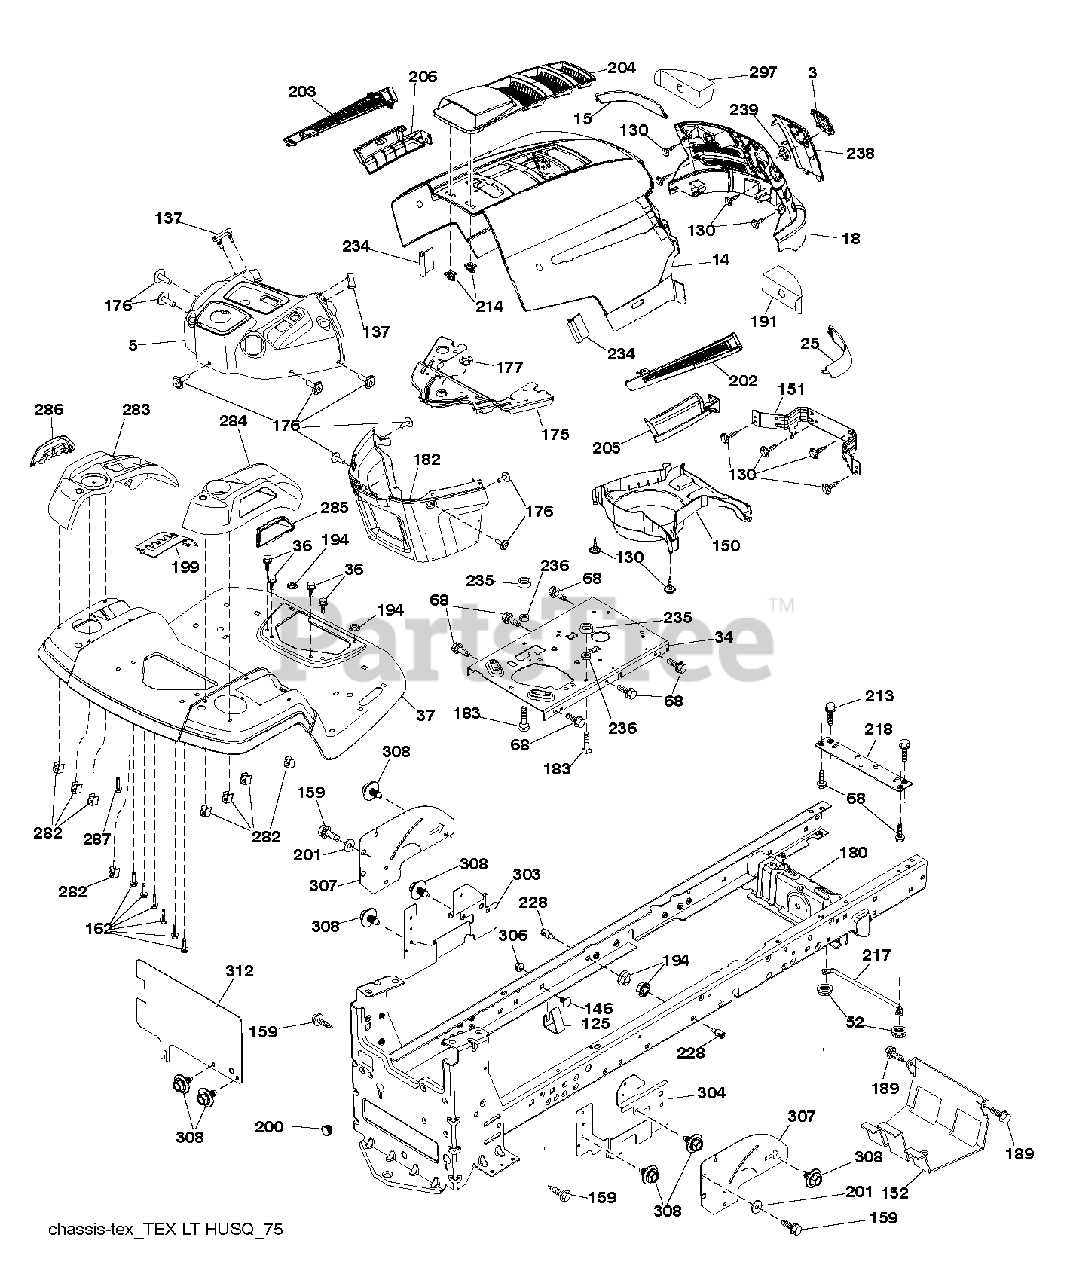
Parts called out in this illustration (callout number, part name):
3	LOGO.HUSQ.GT.LT.CROWN.H
5	DASH.HUSLT.PTO.RS.CHG.SRV.498
14	HOOD.HUSQVARNA.LT.ORANGE
15	LENS.HUSQVARNA LT.RH
18	GRILLE.SVC.HUSQVARNA.GREY
25	LENS.HUSQVARNA LT.RH
34	PLATE.ENGINE.WELDED.CHASSIS
36	SCREW 5/16"
37	FENDER.TLT.FS.W/CUPHLD.ORANGE
52	LOCKNUT
68	SCREW LT
125	CLIP.FUEL.LINE
130	SCREW.#10 X 0.750.BOS
137	BUMPER DASH
146	BOLT.RDHD.SHT.SQNK.3/8-16X5/8
151	BRACKET PIVOT
152	SHIELD.BROWNING.W/TEX
159	SCREW, 3/8-16X3/4
162	SCREW.HI-LO.CONSOLE
175	CROSSMEMBER
176	SCREW.#10-24X5/8.RN.QU
177	BUSHING STEERING
180	CHASSIS
182	DASH.LOWER.PREDATOR LT
183	BOLT.5/16-18X1-1/4 FULL THD
189	SCREW
191	INSERT.REFLECTIVE.RH.
194	NUT LOCK HEX FLANGE 5/16-18
199	PLATE.DECK.LIFT.HUSQ.LT
200	PLUG.DEMO.625
201	WASHER
202	VENT.SIDE.HUSQVARNA.LT.RT
203	VENT.SIDE.HUSQVARNA.LT.LFT
204	SUBASM.TOP.VENT.HUSQ.LT
205	SKIRT.SIDE.HUSQVARNA.LT.RT
206	SKIRT.SIDE.HUSQVARNA.LT.LEFT
213	BOLT
214	CLIP.RETAINER.TINNER.
217	ROD.PIVOT.HOOD
218	X-PIECE.HOOD.STOP.NON/
228	STUD.FASTNER.W/ANTI-ROTATE
234	BUMPER.HOOD.TEX.HUSQVARNA
235	SPACER FENDER
236	NUT.CENTERLOCK.5/16-
238	TRIM.HUSQ LT.668
282	CLIP.RETAINER.CONSOLE.LT.HUSQ
283	CONSOLE.ASM.LFT.RSF.HUSQ.LT
284	CONCOLE.CNTRL.PDL.HUSQ.LT.498
285	CONSOLE INSERT RH
286	CONSOLE.INSRT.LH.HUSQ.LT.BLACK
287	SCREW 1/4X20
297	INSERT REFLECTIVE
303	SHIELD.LWER.LH.LT.GT.NON30.ISO
304	SHIELD.LWR.RH.LT30DECK.PNT.BLK
306	NUT LOCK FLG 3/8-16 UNC
307	SHIELD.UPPER.LT.GT.ISO
308	BOLT, 5/16-18 X 1 3/4
312	SHIELD.PNT.DRAWBAR.FRENCH
